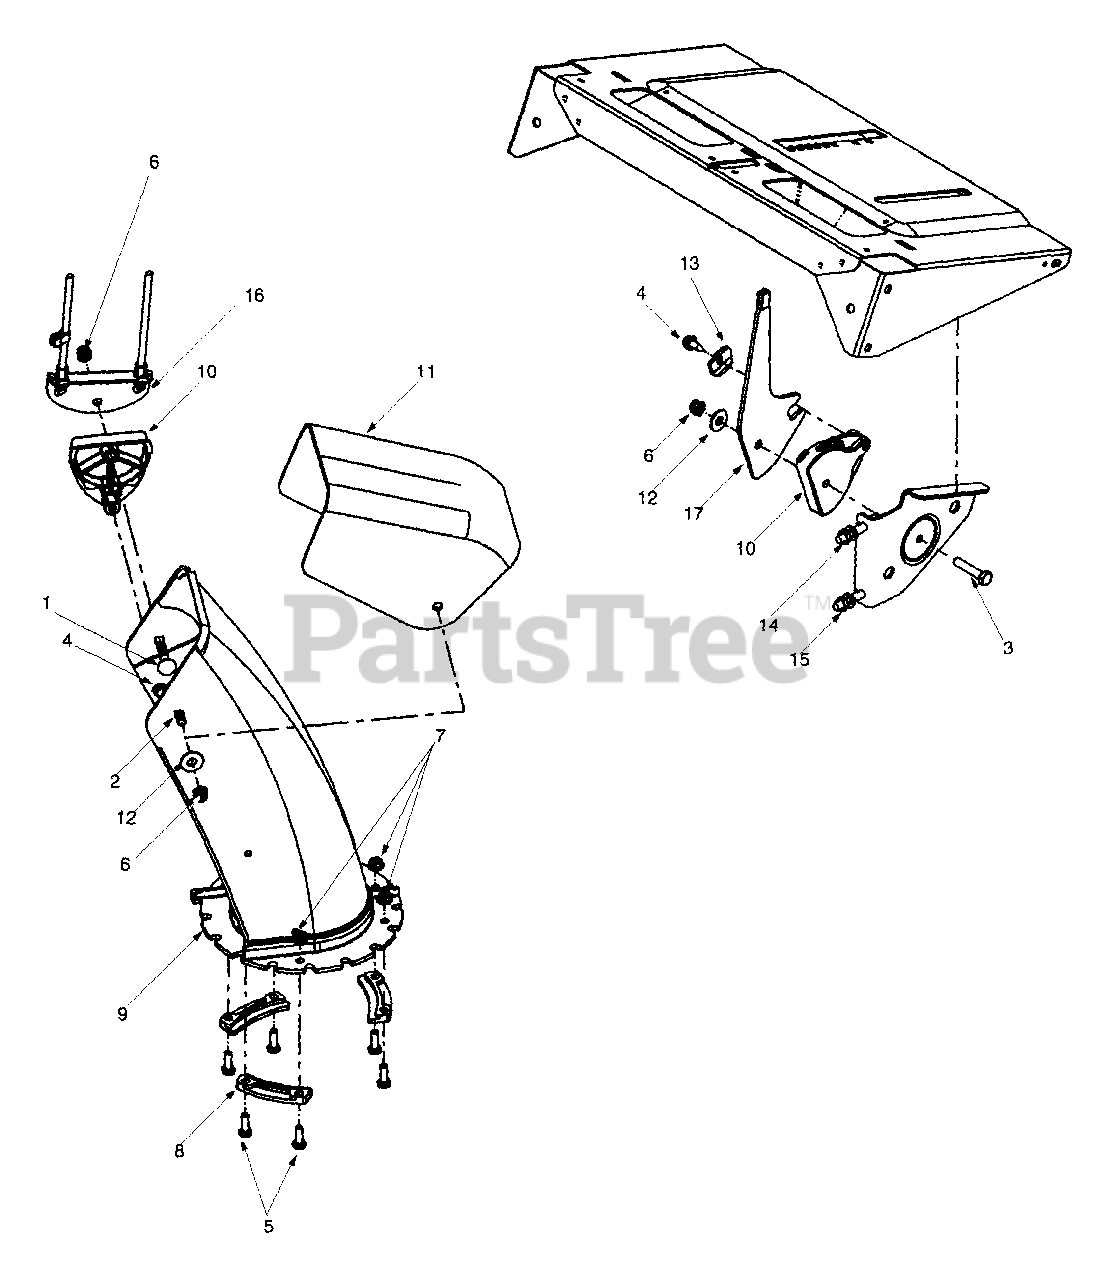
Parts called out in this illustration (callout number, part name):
1	Carriage Bolt: 5/16-18 x 1.5"
2	Carriage Bolt: 5/16-18 x 0.75"
3	Hex Bolt: 5/16-18 x 1.5 Gr. 5
4	Hex Washer Head AB Screw: 1/4-14 x 0.625"
5	Hex Bolt: 1/4-20 x 0.75"
6	Hex Lock Nut: 5/16-18
7	Flange Lock Nut
8	Chute Flange Keeper
9	Lower Chute
10	Chute Tilt Cable Guide
11	Upper Chute
12	5/16 Washer
13	Special Washer
14	Control Cable: Chute Deflector
15	Chute Deflector Cable w/Clip
